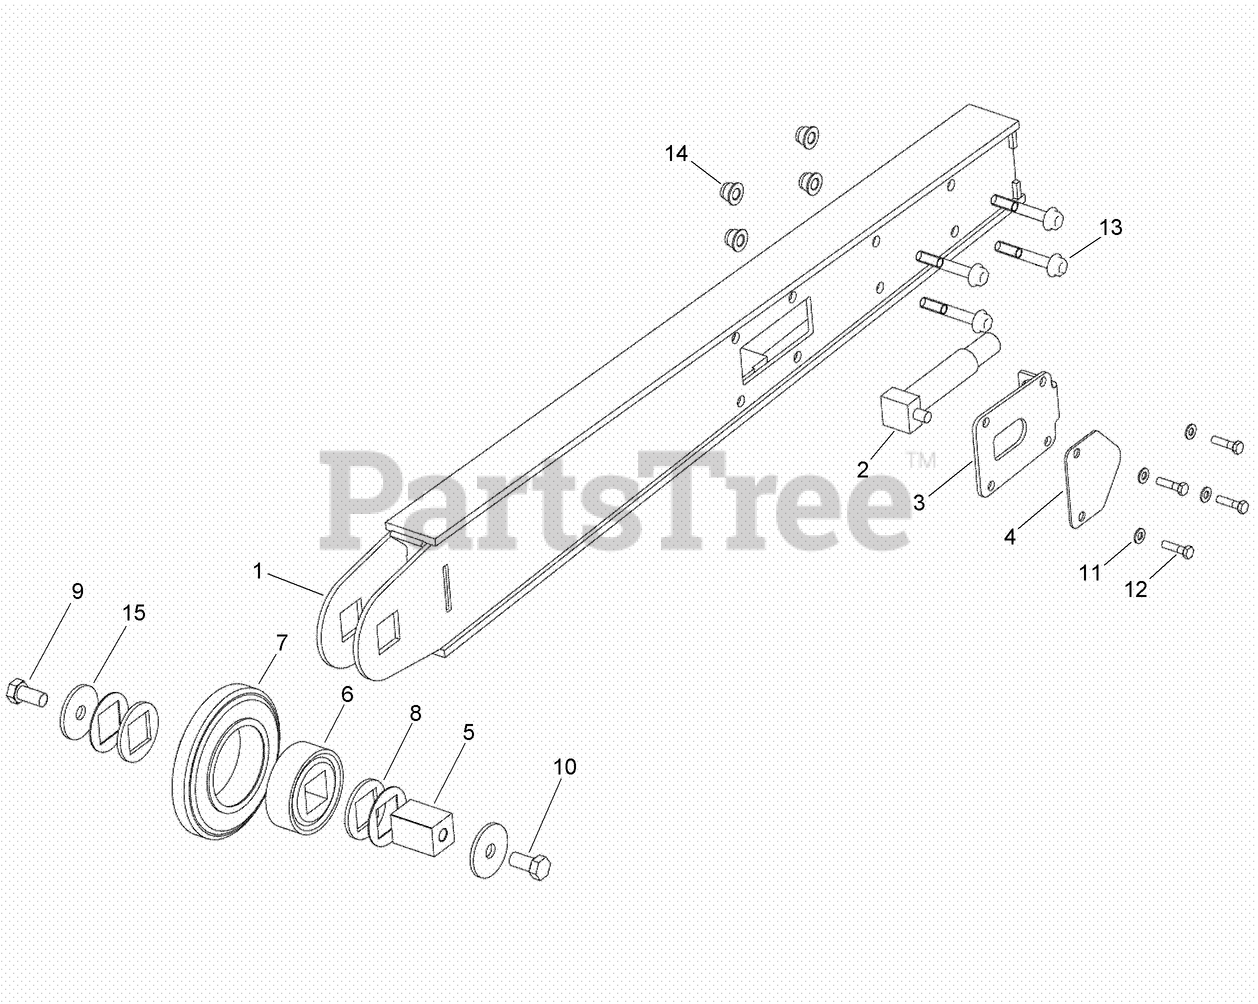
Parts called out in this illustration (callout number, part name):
1	BOOM - 42in Rock
2	PISTON-ADJ
3	PLATE - Piston Keeper
4	PLATE - Cover
5	MOUNT-SHAFT, IDLER
6	BEARING
7	WHEEL-BOOM END, IDLER
8	WASHER
10	BOLT - Hex Hd .625 x 1.25 GR5 ZND
11	WASHER-FLAT
12	BOLT-Hex, 5/16 NC x 1-1/4 inch
13	SCREW-HHF
14	NUT-HHF, LOCK
